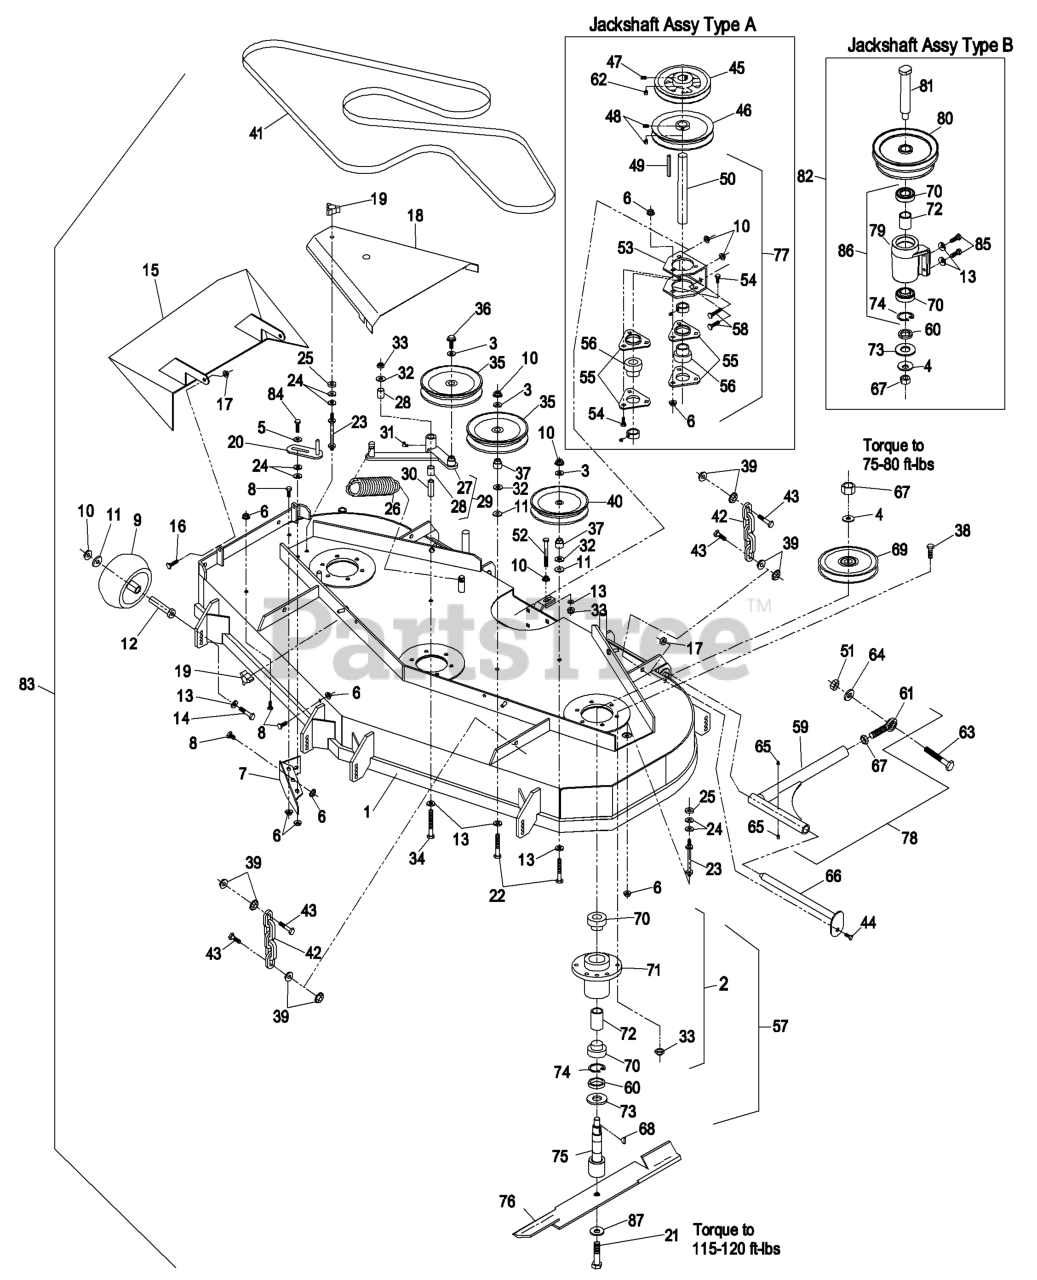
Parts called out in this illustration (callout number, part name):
3	WASHER-FLAT
4	WASHER-SPRING
5	WASHER-SPRING
6	NUT-HF
7	WLD,BAFFLE DISCHARGE
8	SCREW-HH
9	ROLLER-SCALP, ANTI
10	NUT-HHF, WHIZ
12	BUSHING-ROLLER
13	WASHER-BELLEVILLE
14	SCREW-HH
16	SCREW-HH
17	NUT-LOCK, NI
18	SHIELD,BELT
19	KNOB-3 PRONG
20	GUIDE-BELT
21	SCREW-CAP
22	SCREW-HH
23	STUD-SHIELD, BELT (SHORT)
24	WASHER-FLAT
28	SLEEVE-BEARING
30	BUSHING
31	FITTING-GREASE, 90 DEG
32	WASHER-FLAT
33	NUT-LOCK, NI
34	SCREW-HH
36	SCREW-HHF
37	BUSHING-IDLER
38	SCREW-HH
40	PULLEY-IDLER
41	BELT,BLADE DRIVE
42	CHAIN-LIFT, DECK
43	SCREW-CAP, HH
44	SCREW-HH
45	SHEAVE,BLADE DRIVE
46	SHEAVE,SPLIT STEEL
47	SCREW-SET
48	SCREW-SET
49	KEY,MACH 1/4X1/4X2-5/8
50	JACKSHAFT,DECK DRIVE
51	NUT-HEX
52	SCREW-HH
53	BRACKET,JACKSHAFT
54	BOLT-CARR
55	HOUSING-FLANGE
56	BEARING,W/COLLAR
57	ASM,SPINDLE HSG COMPLETE
58	SCREW-CARR
60	SPACER-PULLEY/BEARING
61	BALLJOINT-SPHERICAL
62	SCREW-SET
63	SCREW-HH
64	WASHER-LOCK
65	FITTING-GREASE
66	PIN-STRUT
67	NUT-HEX
68	KEY-WOODRUFF
69	SHEAVE,BLADE DRIVE
70	BEARING
72	SPACER-BEARING
73	GUARD-BEARING, BOTTOM
74	RING-SNAP
77	DK DR. BRG. ASSY
78	STRUT ASM
80	SHEAVE,JACKSHAFT-DOUBLE
81	JACKSHAFT
82	ASM,J-SHFTKIT60,72 3600
83	Complete Deck Assy
84	SCREW-HH
85	SCREW-HH
87	WASHER-BLADE BOLT, HEAVY
